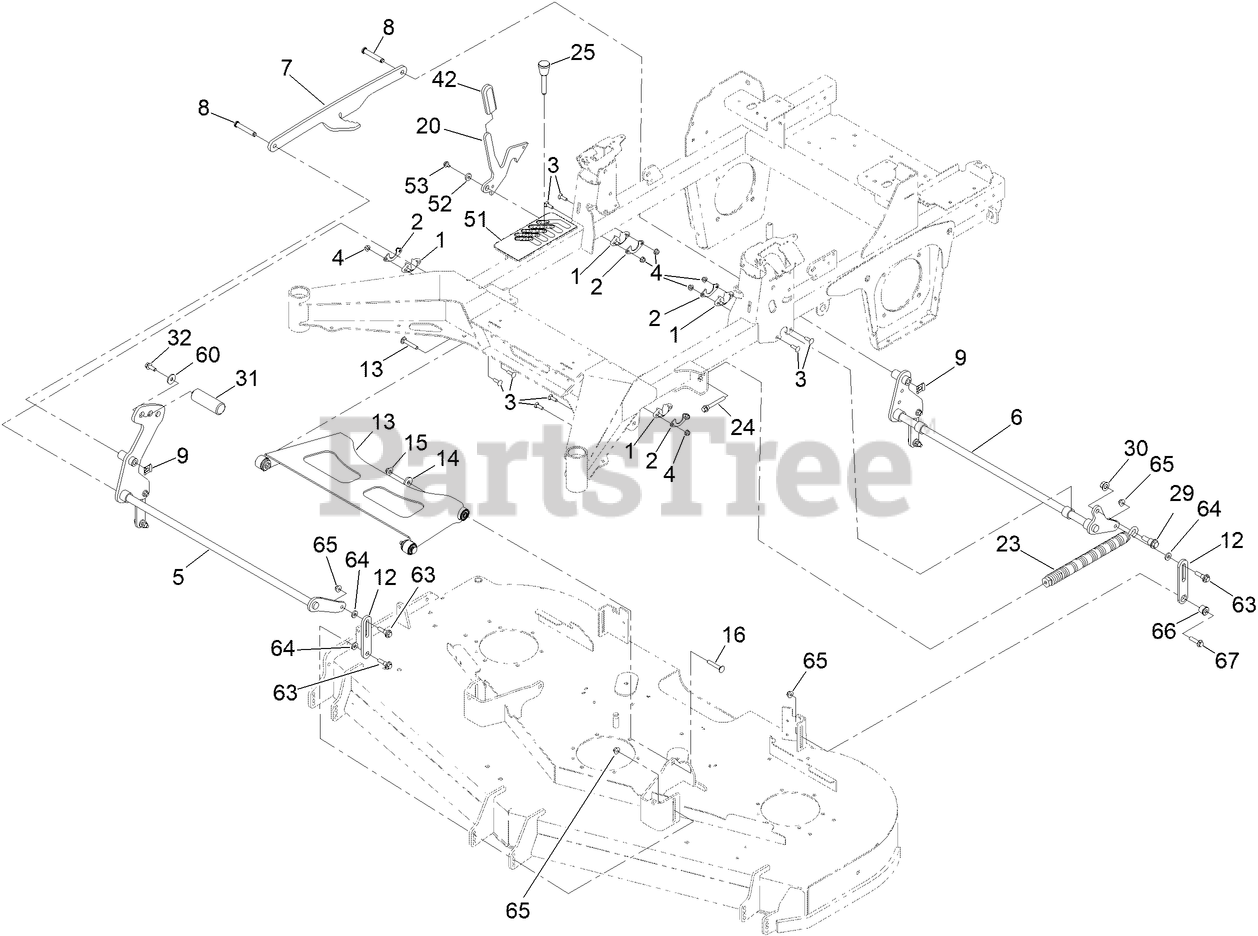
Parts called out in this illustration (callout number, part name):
1	BEARING-FLANGE
2	GUSSET-LIFT, DECK
3	SCREW-CARR
4	NUT-HF, NI
5	DECK LIFT SHAFT ASM, FRT [BLACK
6	DECK LIFT SHAFT ASM [BLACK]
7	LINK-LIFT
8	PIN-CLEVIS
9	CLIP-PIN
12	LINK-LIFT, DECK
13	ASM-DECK STRUT W/ BUSHINGS
14	WASHER
15	NUT-FLANGE, NI
16	SCREW-CARR
20	PLATE-TRANSPORT LOCK
23	SPRING-EXTENSION
24	BOLT-SHOULDER
25	PIN-HOC
29	SCREW-SHOULDER, HHF
30	NUT-LOCK
31	PEDAL-FOOT LIFT
32	SCREW-HHF
42	GRIP-LEVER
51	DECAL-HOC
52	SPACER
53	SCREW
60	WASHER
63	BOLT-SHOULDER
64	SPACER
65	NUT-HF, NI
66	BUSHING-DECK LIFT
67	SCREW-HHF
